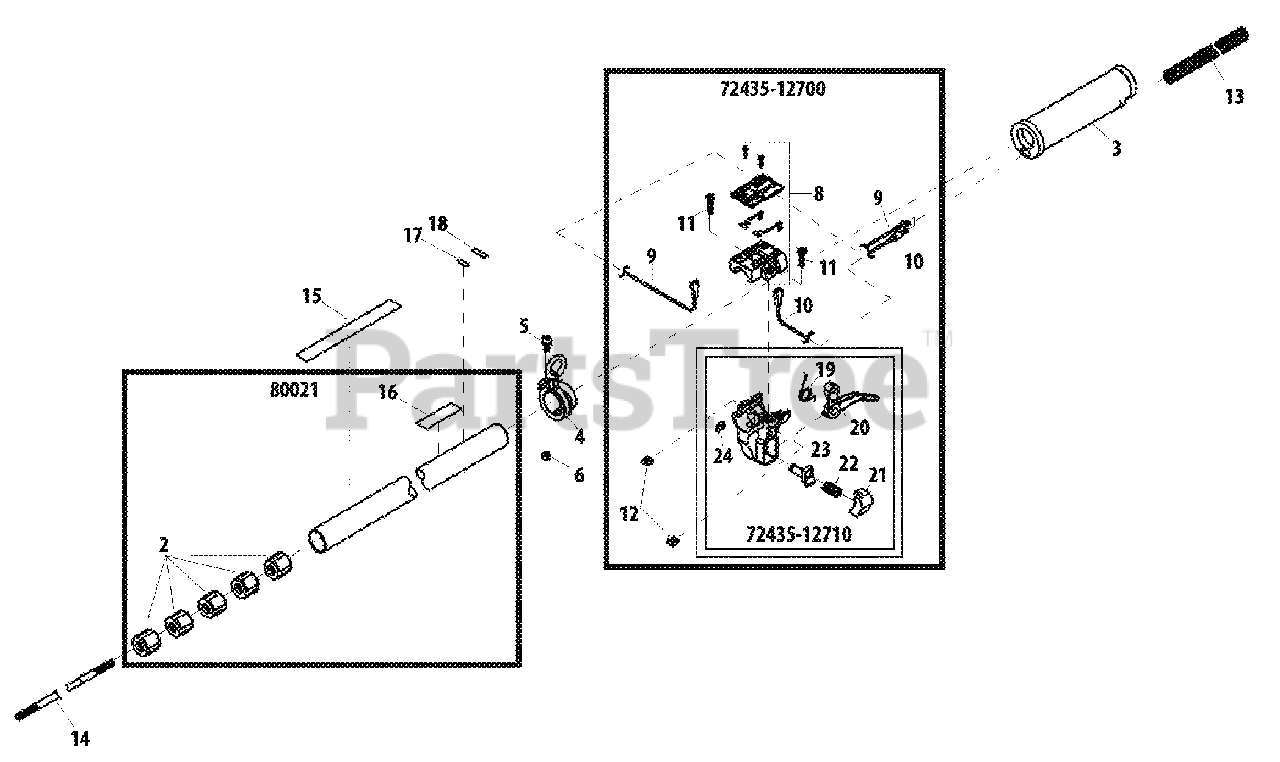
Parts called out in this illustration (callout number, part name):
2	BUSHING
3	GRIP
4	HANGER
5	SCREW - 5X12
8	SWITCH ASSY
9	LEAD - GROUND
10	LEAD - IGNITION
11	SCREW - 5X20
12	NUT
14	PIPE, MAIN
15	LABEL - MODEL
16	LABEL - CAUTION
17	LABEL - INSTRUCTION
18	LABEL - HANDLE LOCATION
19	SPRING, TRIGGER
20	LEVER, THROTTLE
21	BUTTON, THROTTLE LEVER
22	SPRING
24	RING, RETAINING
80021	MAIN PIPE ASSY
7243512700	THROTTLE LEVER ASSY
7243512710	BASE, PURGE
